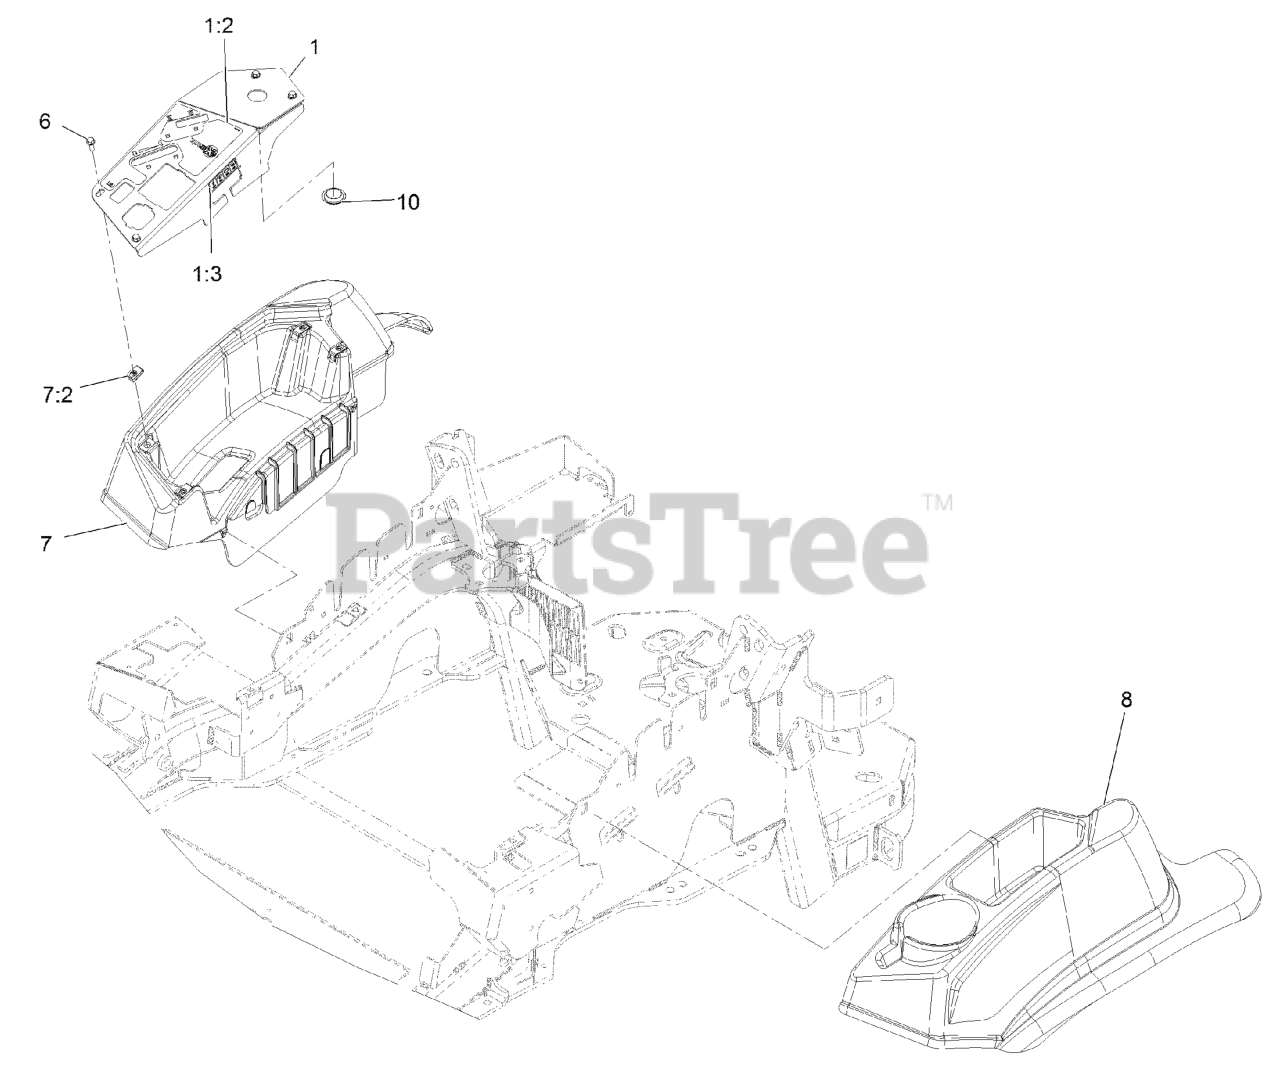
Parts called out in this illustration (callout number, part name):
1	ASM,CONSOLE PANEL W/DECAL
1:2	DECAL-CONTROL PANEL NON-E
1:3	DECAL-FUSES
2	ASM, CHOKE CABLE
3	ASM,THROTTLE CABLE
4	BOLT-CARR
5	NUT-LOCK, NI
6	SCREW-HWH
7	CONSOLE,RH AS ASM
8	CONSOLE, LH AS
9	CLAMP-HOSE
10	PLUG-PLASTIC
11	CLAMP-HOSE
